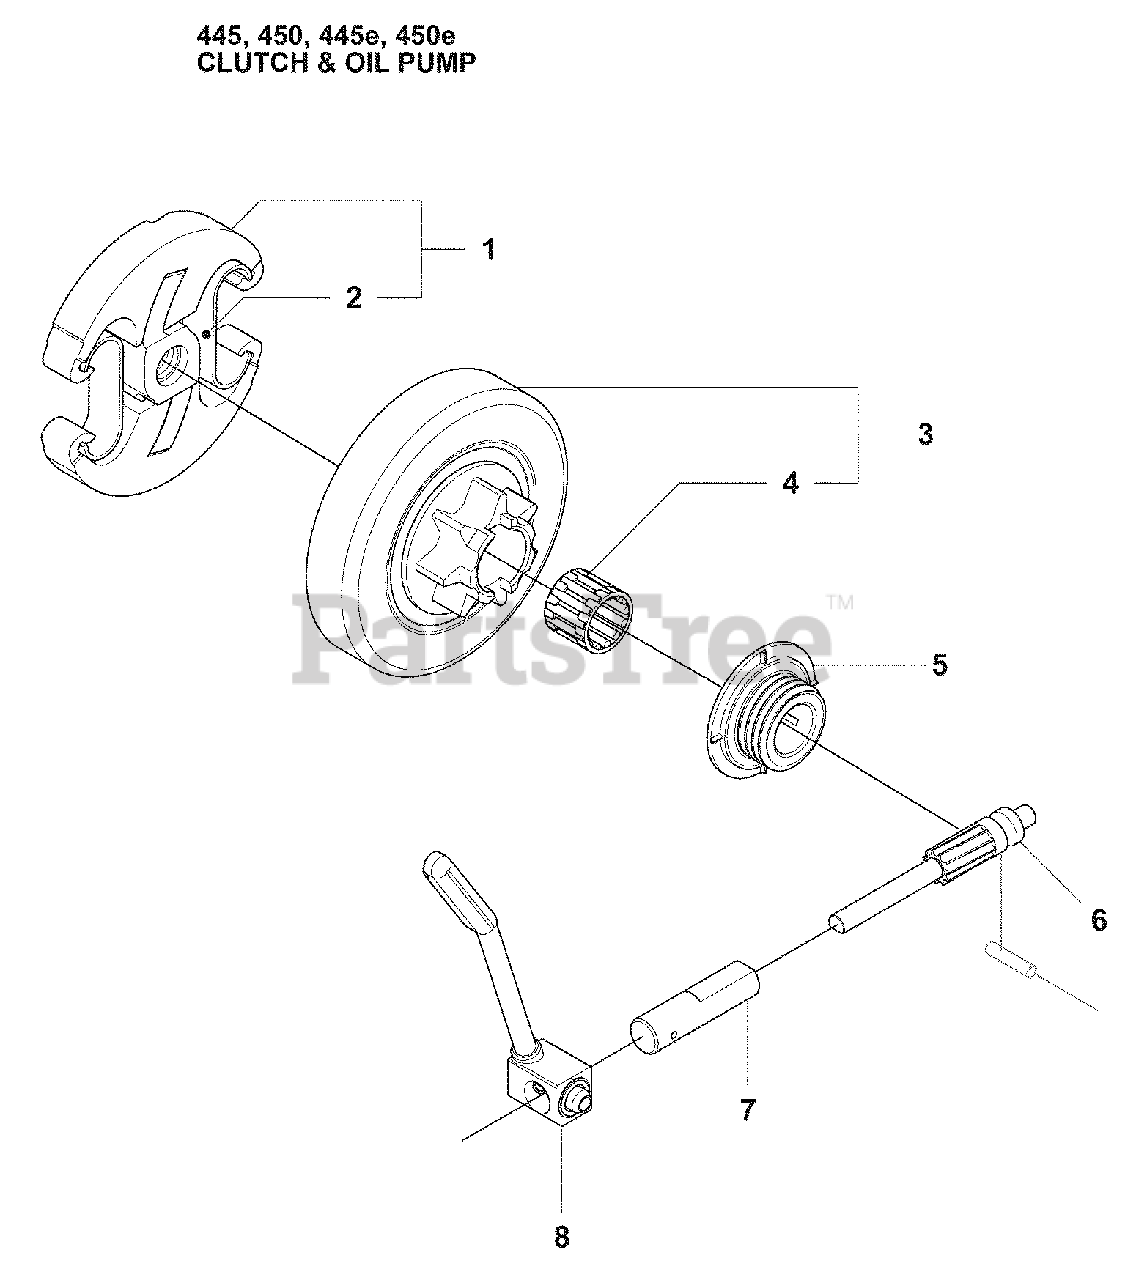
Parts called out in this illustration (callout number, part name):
3	Clutch Drum
4	Needle Bearing
6	Piston Pump
7	Cylinder Pump
